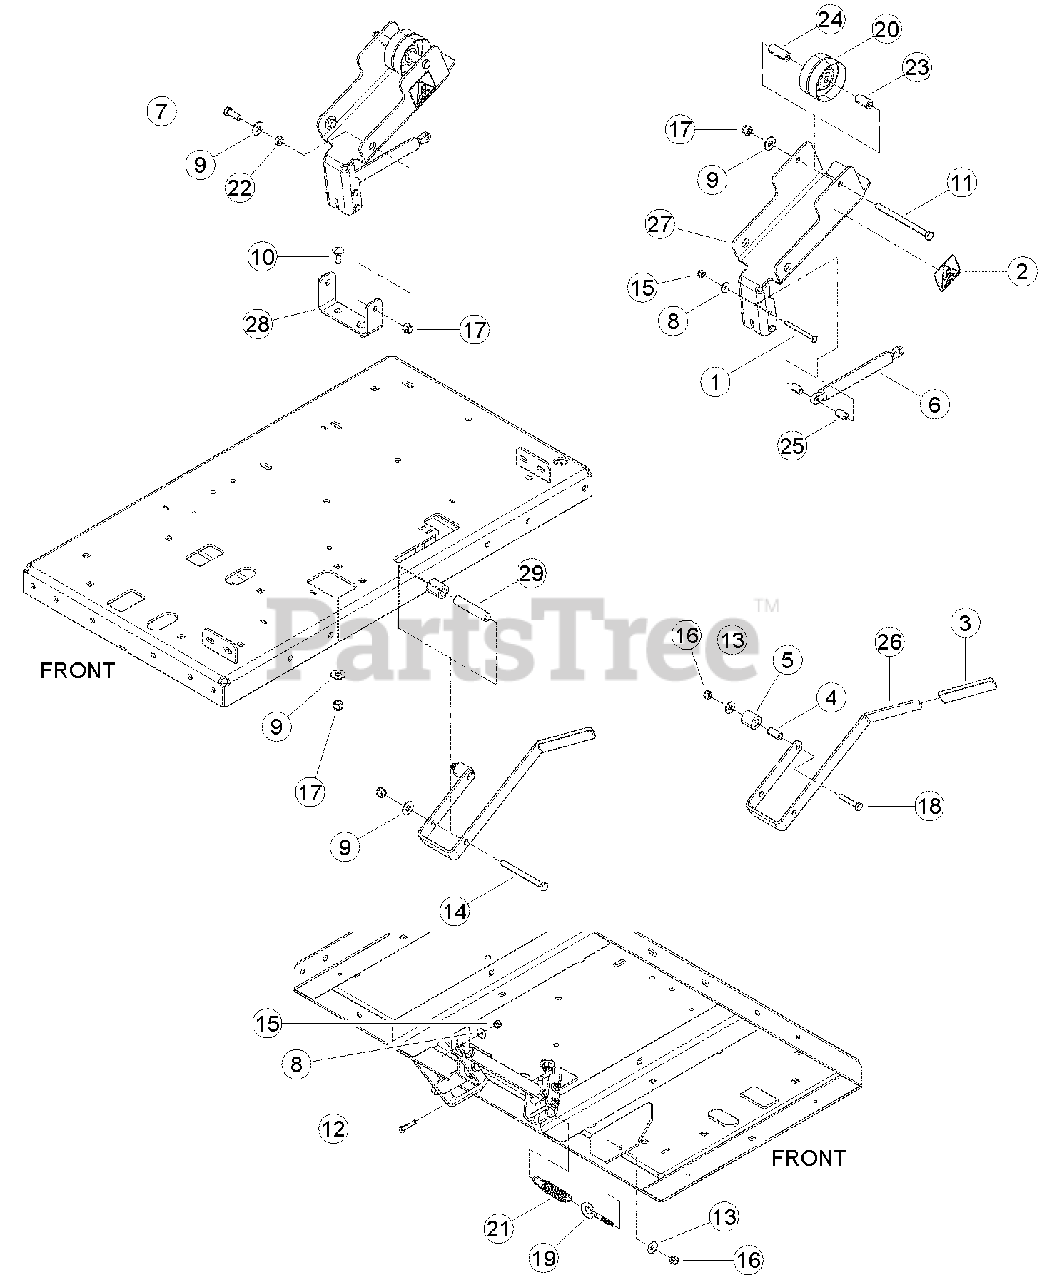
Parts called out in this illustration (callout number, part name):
1	BOLT, 1/4 X 2-3/4 HEX HD GR5 ZP
2	DECAL, SHIELD DANGER ISO
3	GRIP, CLUTCH HANDLE
4	SPACER, 0.5 X 1.00
5	ROLLER, 0.5 X 1.00 X 1.00 NYLON
6	DAMPER, IDLER
7	BOLT, 3/8 X 1 HEX HD GR5 ZP
8	WASHER, 1/4 FLAT ZP
9	WASHER, 3/8 FLAT ZP
10	BOLT, 3/8 X 1 CRG GR5 NC ZP
11	BOLT, 3/8 X 5 HEX HD GR5 ZP
12	BOLT, 1/4 X 1-1/4 HEX HD GR5 ZP
13	WASHER, 5/16 FLAT ZP
14	BOLT, 3/8 X 4 HEX HD GR5 NC ZP
15	NUT, 1/4 NE NYLOCK ZP
16	NUT, 5/16 NE NYLOCK ZP
17	NUT, 3/8 NE NYLOCK ZP
18	BOLT, 5/16-18 X 1-3/4 HEX HD GR5 ZP
19	I-BOLT, 5/16-18 X 2 LONG ZP
20	PULLEY, 3-1/4 FLAT IDLER
21	SPRING, 3/4" OD EXTENSION
22	SPACER, IDLER PIVOT
23	IDLER SPACER
24	SPACER .63 X 1.63
25	SPACER, .50 X .775
26	LEVER, CHIPPER ENGAGEMENT
27	BRACKET, IDLER
28	ANCHOR, IDLER
29	SPACER, .63 X 3.060
